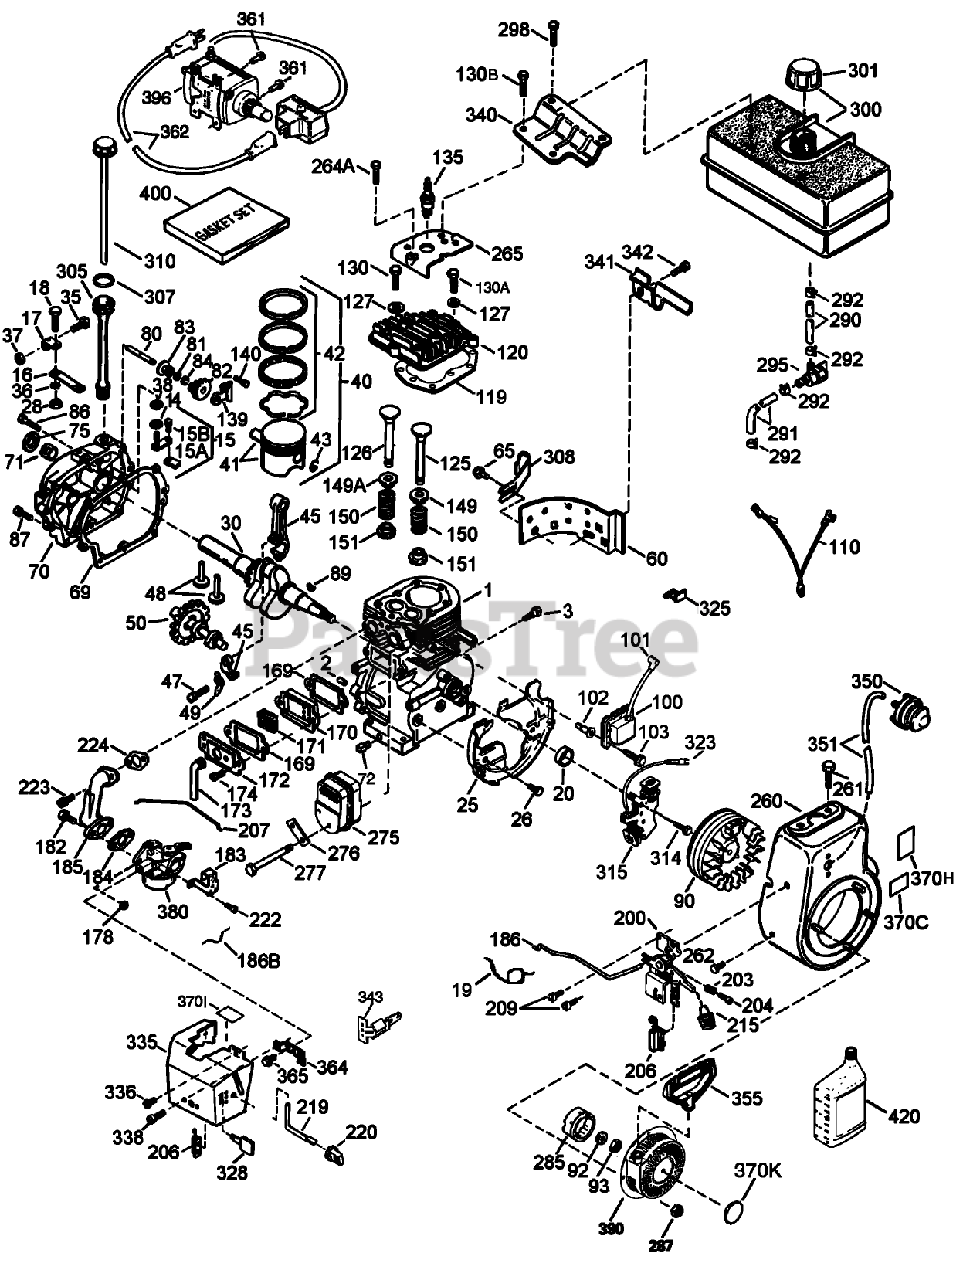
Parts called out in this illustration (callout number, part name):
1	Cylinder Asm (Includes 2, 20, 72)
2	Pin-Dowel
3	Screw (1/4-20x1/2)
14	Washer-Flat
15	Rod, Governor (Incl. Nos.62 63)
15A	Yoke-Governor
15B	Screw (6-40x5/16)
16	Lever-Governor
17	Clamp-Lever, Governor
18	Screw (T-15, 8-32x7/16)
19	Spring-Throttle
20	Seal-Oil
25	Baffle-Housing, Blower
26	Screw (1/4-20x19/32)
28	Nut-Lock
30	Crankshaft
35	Screw
36	Washer-Lock
37	Nut-Lock
38	Ring-Retaining
40	TANK PAD
40	Piston- Pin and Ring Set (.010 O S)
41	Piston and Pin ASM (STD) (Includes 43)
41	J-BOLT
42	BUSHING TRANS 7/8 BORE
42	BUSHING - ENG 1" BORE
45	Connecting Rod Asm (Includes 47, 49)
47	Bolt-Rod, Connecting
48	Lifter-Valve
49	Dipper-Oil
50	Camshaft (MCR)
60	Extension-Housing, Blower
65	Screw
69	Gasket-Cover, Cylinder
70	Cylinder Cover ASM (Incl. Ref. #71, 75 and 80-84)
71	2025A77 WIZARD ROTA
72	Plug-Drain, Oil (SQH 1/4-18)
75	Seal-Oil
80	Shaft-Governor
81	Washer
82	Governor Gear ASM
83	Spool-Governor
84	Ring-Retaining
86	Screw (1/4-20x1-3/16)
87	Screw (1/4-20x1-11/16)
89	Key-Flywheel
90	Flywheel ASM
92	Washer-Belleville
93	Nut-Flywheel
100	Ignition-Solid State
101	Cover-Spark Plug
102	Stud-Mounting, Solid State
103	Screw (T-15, 10-24 x 15/16)
110	Wire-Ground
110A	Wire-Ground
119	Gasket-Head, Cylinder
120	Head-Cylinder
125	Valve, Exhaust (Standard)(Incl. No. 9)
125	Valve, Exhaust (1/32" oversize)(Incl. No. 9)
126	Valve, Intake (Std.) (Incl. Ref. #58)
127	Washer-Flat
130	Screw (5/16-18x1-1/2)
130A	Screw (5/16-18x1-25/32)
130B	Screw (5/16-18x39/64)
135	Spark Plug-Resistor (R J19 L M)
139	Bracket-Gear, Governor
140	Screw (10-24x1/2)
149	Cap-Spring, Valve
149A	51106 GILSON ROTARY
150	Spring-Valve
151	Keeper-Spring, Valve
169	Gasket-Cover, Valve
170	Body-Breather
171	Element-Breather
172	Cover-Valve
173	Tube-Breather
174	Screw
178	Nut and Lock Washer (1/4-28)
182	Screw (1/4-28x1)
183	Bracket-Choke
184	Gasket-Carburetor To Intake Pipe
185	Pipe-Intake
186	Link-Governor
186B	Spring-Choke
200	Bracket-Control (Includes 19, 203, 204, 206)
203	Spring-Compression
204	Screw (T-10, 5-40x7/16)
206	Terminal
